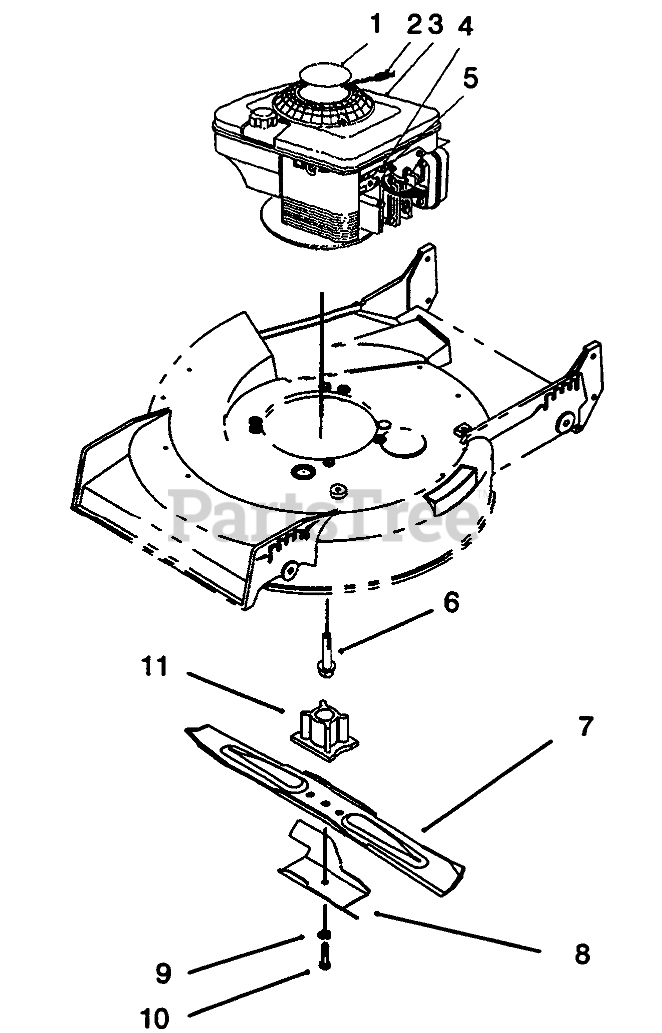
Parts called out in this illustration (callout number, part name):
1	DECAL-ENG F/W ENGINE
2	STOP-ROPE
4	CLAMP-CASING
5	Screw
6	SCREW-HWH
7	Blade
8	Accelerator
9	WASHER-LOCK
10	SCREW-BLADE
11	BLADE RETAINER
